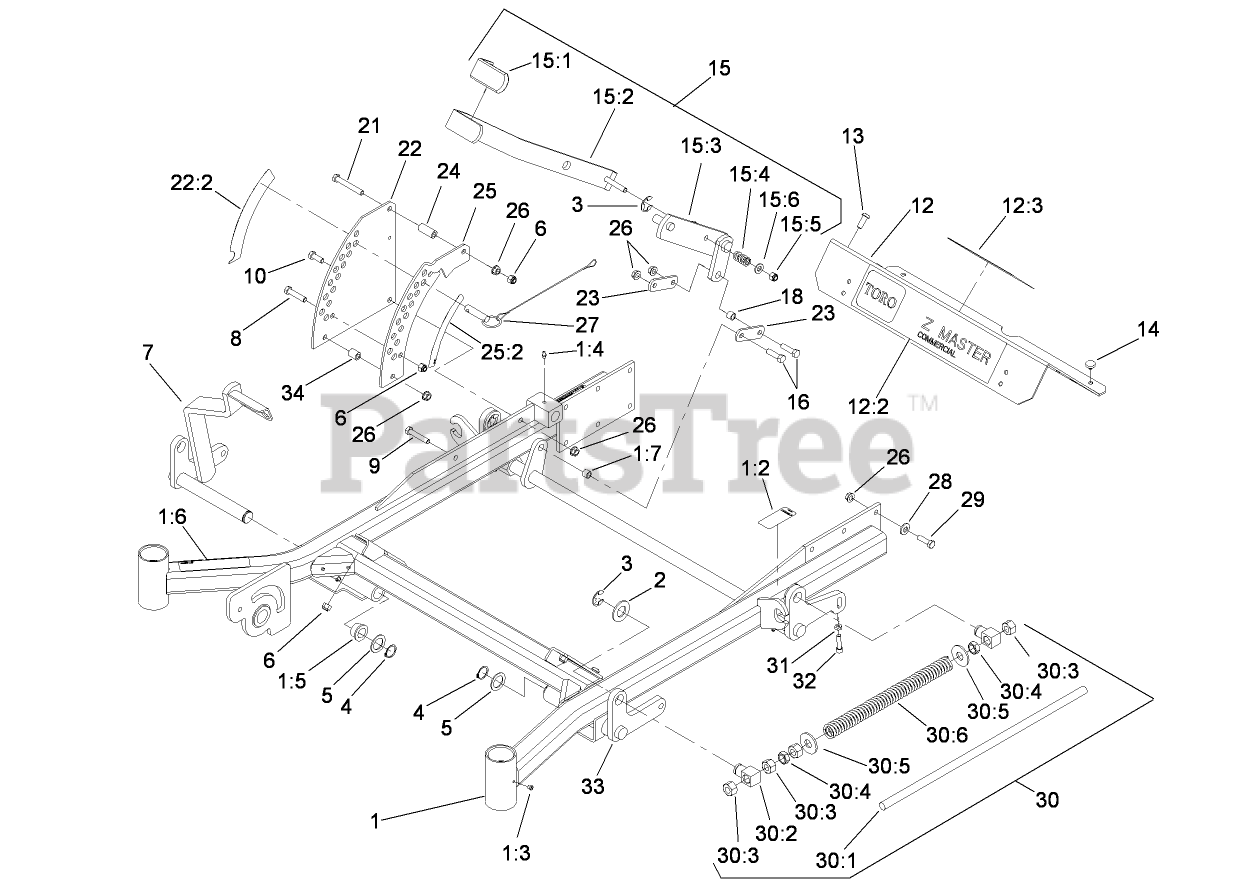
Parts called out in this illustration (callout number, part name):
1	FRAME ASM
1:2	DECAL-BRAKE, PARKING
1:4	FITTING-GREASE
1:5	BUSHING
1:6	DECAL-WARNING
1:7	Bushing
2	WASHER-FLAT
3	RING-RETAINING, EXT
4	RING-RETAINING
5	WASHER-SPACER
6	NUT-LOCK, NI
7	LIFT-DECK, RH FRONT
8	SCREW-HH
9	SCREW-HH
10	SCREW-HH
12	FOOTREST
12:3	DECAL-DANGER, SLOPE
13	SCREW-HSBH
14	BUMPER
15	DECK LIFT HANDLE ASM
15:1	GRIP-LEVER, LIFT
15:2	LEVER-LIFT
15:3	ARM-LIFT, DECK
15:4	SPRING-COMPRESSION
15:5	NUT-LOCK, NI
15:6	WASHER-FLAT
16	SCREW-HH
18	Bushing
21	SCREW-HH
22	LIFT PLATE-DECK, OUTER
22:2	DECAL-HEIGHT, DECK
23	ARM-LIFT, DECK
24	BUSHING-LEVER, LIFT
25	PLATE-DECK LIFT, INNER (CE)
25:2	DECAL-HEIGHT, DECK
26	NUT-HHF, WHIZ
27	Hitch Pin ASM
28	WASHER-BELLEVILLE
29	SCREW-HH
30	Front Frame Spring ASM
30:1	ROD-LIFT, DECK
30:2	SWIVEL-DECK MOUNT, REAR
30:3	NUT-HEX
30:4	NUT-JAM
30:5	WASHER-FLAT
30:6	SPRING-SUPPORT, DECK
31	NUT-JAM
32	SCREW-HSH
33	LIFT-DECK, LH
34	BUSHING-LEVER, LIFT
